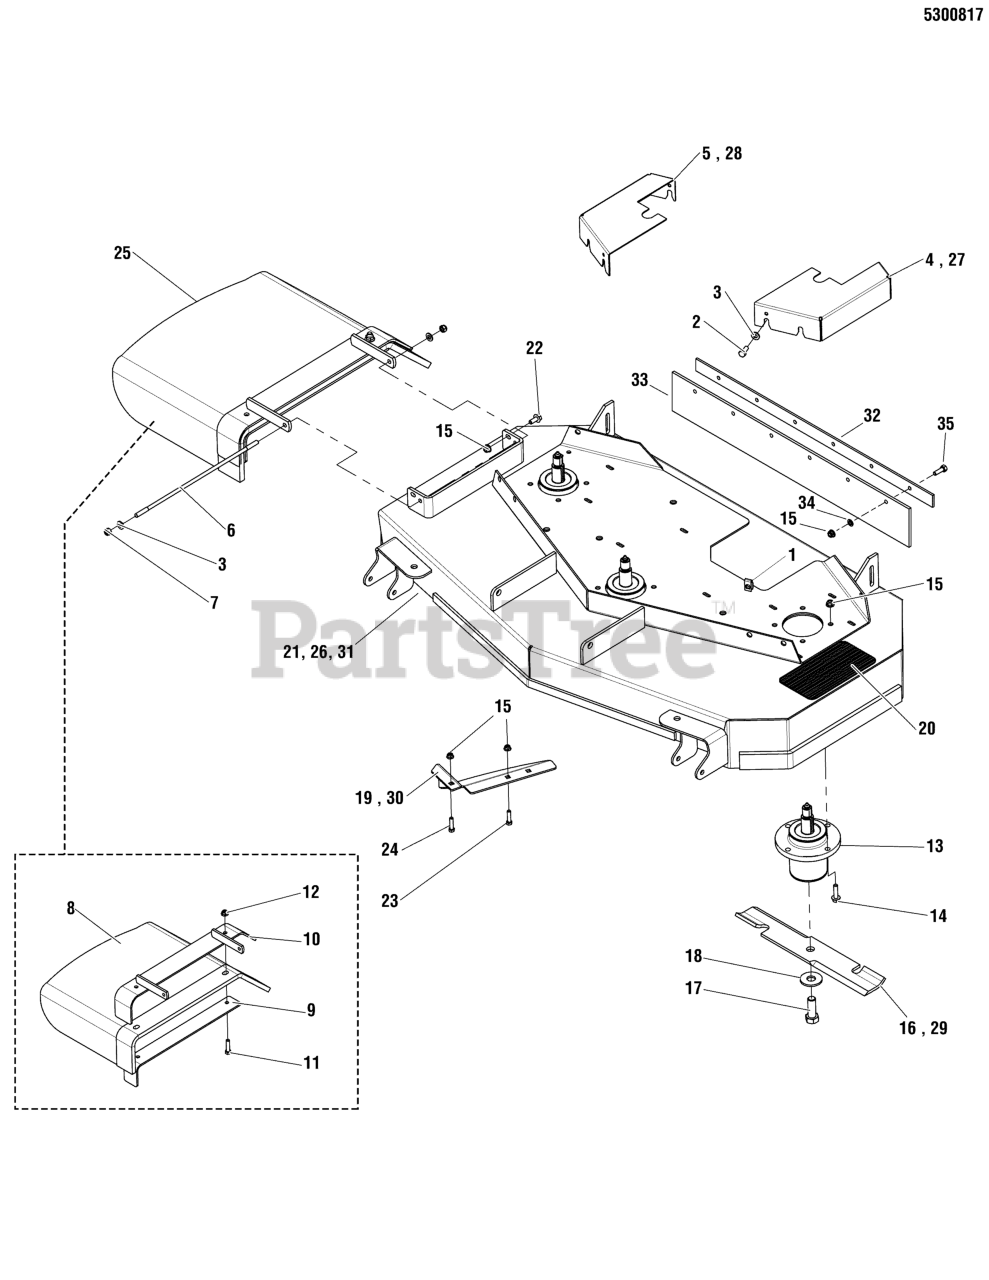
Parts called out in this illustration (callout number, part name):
1	BODY CLIP, 5/16-18-7GA MATERIAL
2	BOLT, 5/16-18 X 3/4 GD5
3	WASHER, 5/16" SAE
4	GUARD, 44" MOWER DECK, LH
5	GUARD, 44" MOWER DECK, RH
6	ROD, 5/16 X 13.75, TBE
7	NUT, 5/16-24 HEX NYLON LOCK
8	CHUTE, DISCHARGE, BEND RUBBER, 44/48/52
9	SUPPORT, DISCHARGE CHUTE, 44/48/52 - BLK
10	WELD, MOUNT, DISCHARGE CHUTE - BLK
11	BOLT, 3/8-16 X 1-1/2" GD5 CZ
12	NUT, 3/8-16 HEX NYLOCK FLANGE
13	ASSM, SPINDLE, LOW PROFILE
14	BOLT, 5/16-18 X 1 1/4 FLANGE
15	NUT, 5/16-18 HEX NYLOCK FLANGE
16	BLADE, 15" (SET OF THREE)
17	BOLT, 5/8-11 X 1-3/4 GD8
18	WASHER, 5/8 GRADE 8, YZ
19	WELD, DISCHARGE BAFFLE, 44" - BLK
20	SAFETY WALK, 4.00 X 7.50
21	DECK SHELL W/DECALS, 44, IS500Z
22	BOLT, 5/16-18 X 3/4 GD5
23	BOLT, 5/16-18 X 1, CARRIAGE
24	BOLT, 5/16-18 X 3/4, CARRIAGE
25	KIT, DISCHARGE CHUTE, 44/48/52
26	DECK SHELL W/DECALS
27	GUARD, 52" DECK - LH
28	GUARD, 52" DECK - RH
29	BLADE, 18" (SET OF THREE)
30	PLATE, DEFLECTOR, 52" - BLK
31	DECK SHELL W/DECALS
32	PLATE, SUPPORT, 48 - BLK
33	FLAP, RUBBER, 48"
34	5/16 PUSH-ON NUT RETAINER, STL, CZ
35	BOLT, 5/16-18 X 1 GD5 Y
